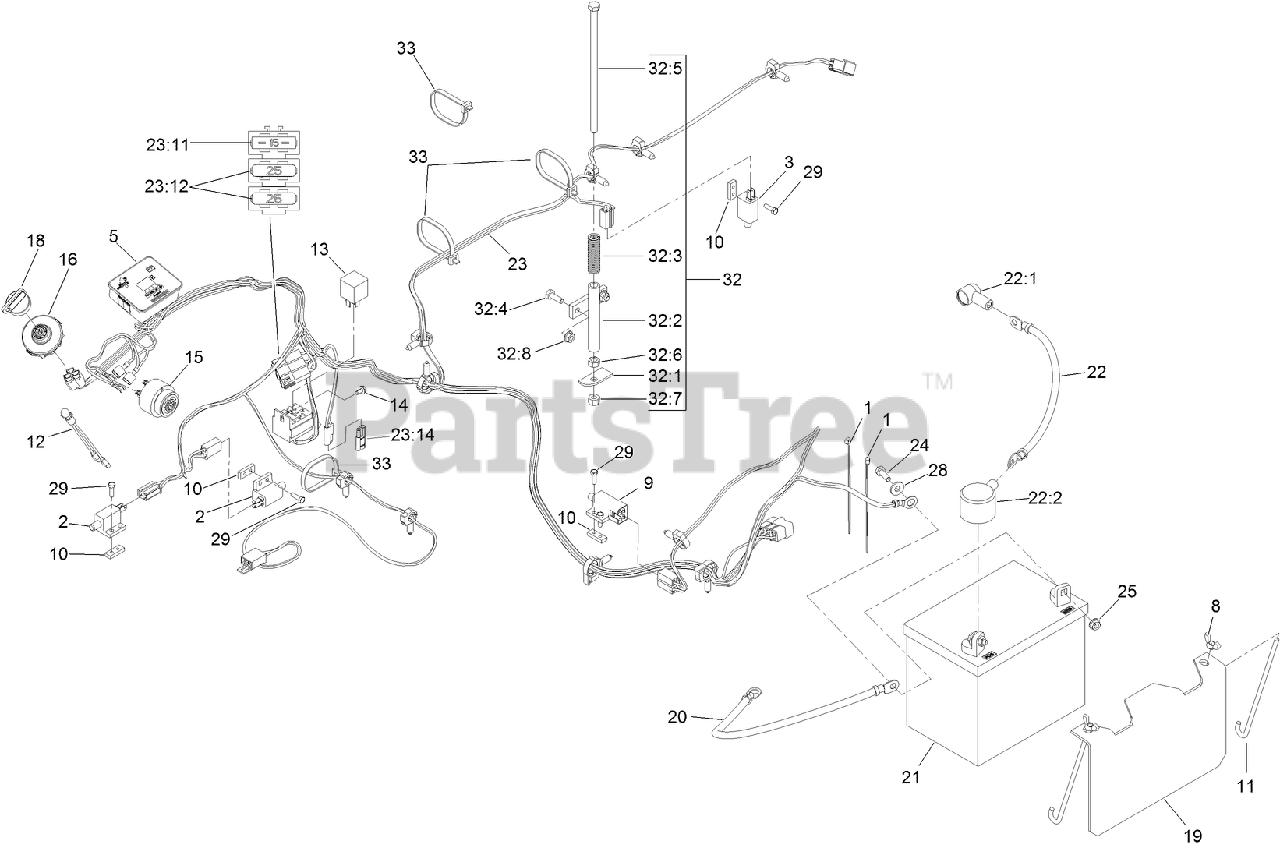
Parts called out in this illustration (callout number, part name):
1	TIE-CABLE
2	SWITCH-OPEN, NORMALLY
3	SWITCH-CLOSED, NORMALLY
5	HOUR METER ASM
8	WINGNUT
9	SWITCH
10	PLATE-TAPPED
11	BOLT-HOLDDOWN
12	INDICATOR-LED, RED
14	SCREW-HWH
15	ALARM-TONE, DUAL
16	SWITCH-IGNITION
18	KEY-IGNITION
19	HOLD DOWN-BATTERY
20	CABLE-BATTERY, NEGATIVE
21	BATTERY (300 CCA, WET)
22	CABLE-BATTERY, POSITIVE
22:1	INSULATOR-SOLENOID
22:2	INSULATOR-BATTERY
23	HARNESS-WIRING
23:11	FUSE-BLADE, 15 AMP
23:12	FUSE-BLADE, 25 AMP
23:14	CAP-PLUG
24	SCREW-HH
25	NUT-HF
28	WASHER-FLAT
32	HOPPER SWITCH ACTUATOR ASM
32:1	PLATE-SWITCH
32:2	MOUNT-SPRING, SEAT
32:3	SPRING-SWITCH, SEAT
32:4	SCREW-HH
32:5	SCREW-HH
32:6	NUT-HEX
32:7	NUT-LOCK, NI
32:8	NUT-HF
33	TIE-PLASTIC
